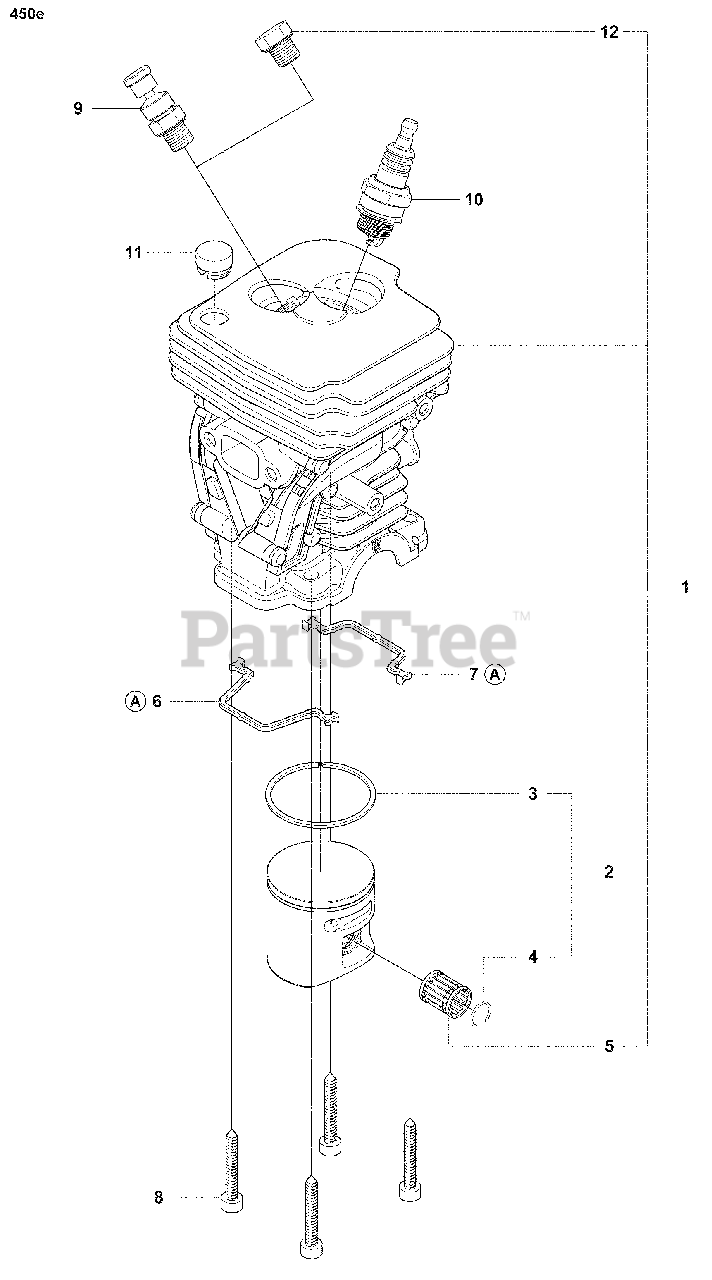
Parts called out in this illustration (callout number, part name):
2	Piston Assembly
3	Piston Ring
4	Circlip, 10mm
5	Support Bushing
9	Decompression Valve
10	Solid Spark Plug, BPMR7A
12	Cylinder Plug
